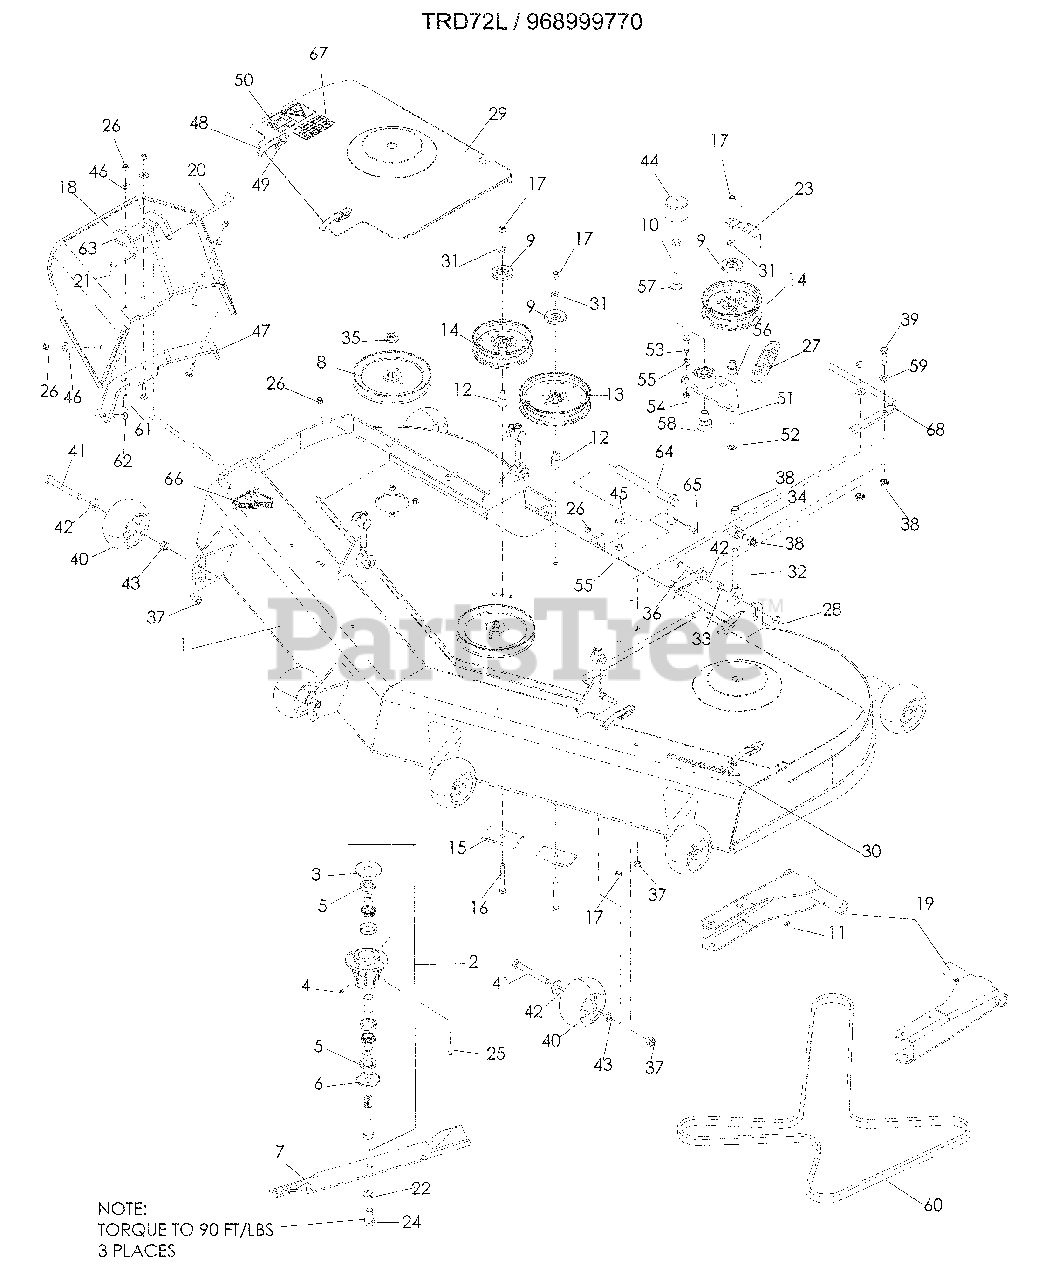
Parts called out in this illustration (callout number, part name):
1	DECK w/ DECALS
2	HOUSING ASSEMBLY
3	DUST CAP, TOP
4	GREASE POPPET
5	SEAL, SHAFT
6	DUST CAP, BOTTOM
7	BLADE, 25"
8	PULLEY, 72"
9	SHIELD, DUST
10	HCS ½-13 x 3¼
11	ZERK
12	IDLER BUSHING
13	IDLER PULLEY
14	IDLER PULLEY
15	PAD
16	HCS 3/8-16 x 3
17	NUT 3/8-16 NYLOC
18	DISCHARGE CHUTE
20	PIN, CHUTE PIVOT
21	PIN, COTTER, 1/8 x ¾
22	LOCKWASHER 5/8
23	GUIDE, BELT
24	HCS 5/8-18 x 1¼
25	HCS 5/16-18 x 1¼
26	NUT 5/16-18 NYLOC
28	NUT 7/16-14 CTRLK, GR A
29	BELT SHIELD, RIGHT
30	DECAL, TUNNEL RAM
31	WASHER 3/8 THICK
35	NUT ¾-16 FLANGE
36	HCS 3/8-14 x 1¾
37	NUT ½ NYLOC
38	NUT ¼-20, FLANGE
39	HCS ¼-20 x 1
40	WHEEL GAUGE
41	HCS ½-13 x 4
44	CAP, VINYL
45	HCS 3/8-16 x 1¼
46	WASHER 5/16
47	REINFORCEMENT, BRACKT
48	DRAW LATCH
49	BLIND RIVET
50	DECAL, SEVERING
51	ARM w/ BEARINGS, IDLER
52	RHSNB 3/8-16 x 2¾
53	HCS 3/8-16 x 1½ GR8
54	NUT 3/8-16 JAM
55	NUT 3/8-16 WHIZLK
56	BUSHING, IDLER
57	WASHER ½ BELLEVILLE
58	PIVOT, BEARING
59	WASHER ¼ SAE
61	RHSNB 5/16-18 x 1½
62	RHSNB 5/16-18 x 1¼
63	BRACKET, RUBBER CHUTE
65	HCS 5/16-18 x 1
66	DECAL, CPSC
67	DECAL, WARNING
68	BELT GUIDE
